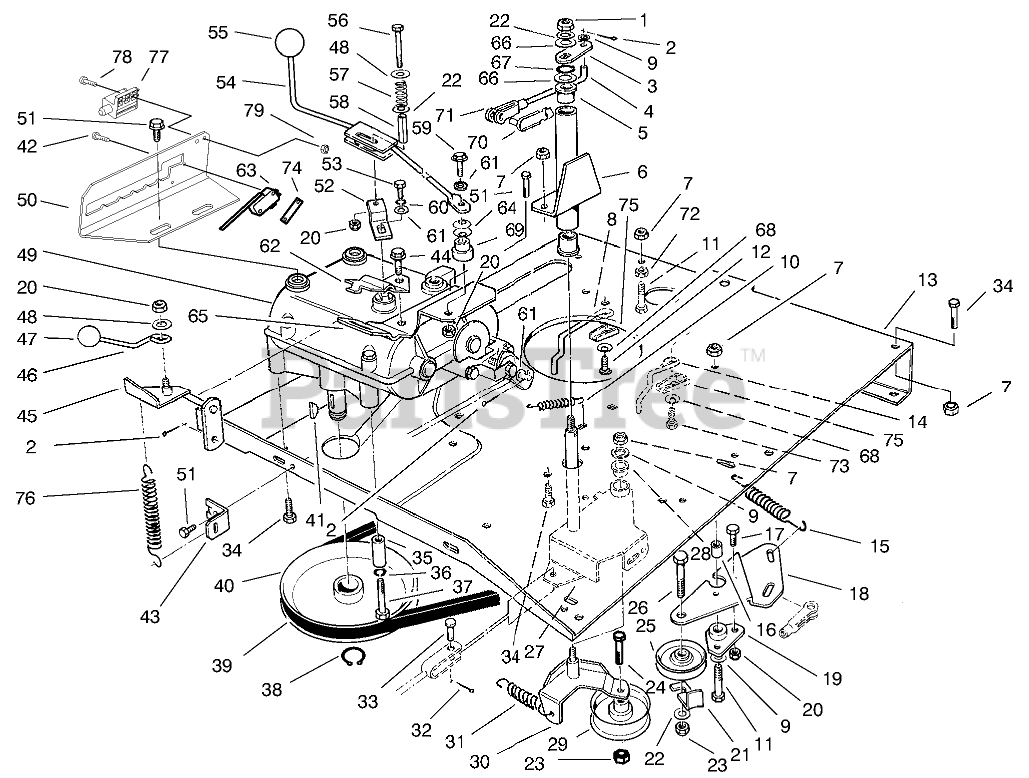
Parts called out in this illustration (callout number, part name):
1	NUT-LOCK, NI
2	PIN-COTTER
3	BRKT-DECK ENGAGE BLK
4	LINK-DECK ENGAGE
5	BUSHING-FLANGE
6	Tube W.A.-Pivot (Incl. Ref. #5)
7	NUT-LOCK, NI
8	GUIDE-BELT
9	WASHER-PLAIN
10	SPRING-RETURN, BRAKE
11	SCREW-HH
12	SCREW-HWHTF
13	PLATE-ENGINE
14	GUIDE-ENG. BELT L.
15	SPRING-TRACTION
16	SPACER-PIVOT
17	SCREW-HH
18	PLT-IDLER MTG
19	MOUNT-TRACTION PIVOT
20	NUT-LOCK, NI
21	RETAINER-BELT
22	WASHER-FLAT
23	NUT-LOCK, NI
24	SCREW-HH
25	PULLEY-IDLER
26	SCREW-HH
27	Bracket-Arm, Idler (Incl. Ref. #28)
28	BUSHING-FLANGE
29	PULLEY-IDLER
30	IDLER MTG PLT WA (BLACK)
31	SPRING-IDLER
32	PIN-COTTER
33	PIN-CLEVIS
34	SCREW-HH
35	GUIDE-BELT
36	WASHER-LOCK
37	SCREW-HH
38	RING-SNAP, EXTERNAL
39	67BELT, TRACTION DRIVE
40	PULLEY
41	KEY-WOODRUFF
42	Screw
43	BRKT-SPRING MT
44	SCREW-HWHTF
45	DECK ENGAGE LEVER WA (BLACK)
46	ROD-ENGAGE
47	KNOB-CONTROL
48	WASHER-FLAT
49	TRANSMISSION
50	GATE-SHIFT
51	SCREW-HWHTF
52	LEVER-SHIFT
53	SCREW-HH
54	SHIFT LEVER WA (BLACK)
56	SCREW-HH
57	SPRING-COMPRESSION
58	SPACER-SPLIT
59	SCREW-HH
60	WASHER-LOCK
61	WASHER-FLAT
62	BRKT-DECK ENG UPPER
63	SWITCH-MICRO
64	WASHER-BELLEVILLE
65	BRKT-DECK ENG. SHIFTER
66	WASHER
67	RING-RETAINING
68	WASHER-BELLEVILLE
69	SPACER-PIVOT
70	CLEVIS PIN ASM
71	CLEVIS-ADJ
72	NUT-JAM
73	BOLT-CARR
74	NUT-SPEED
75	ANCHOR-GUIDE, BELT
76	SPRING-DOOR
77	SWITCH-POLE, SINGLE
78	SCREW-SHH
79	NUT-LOCK
